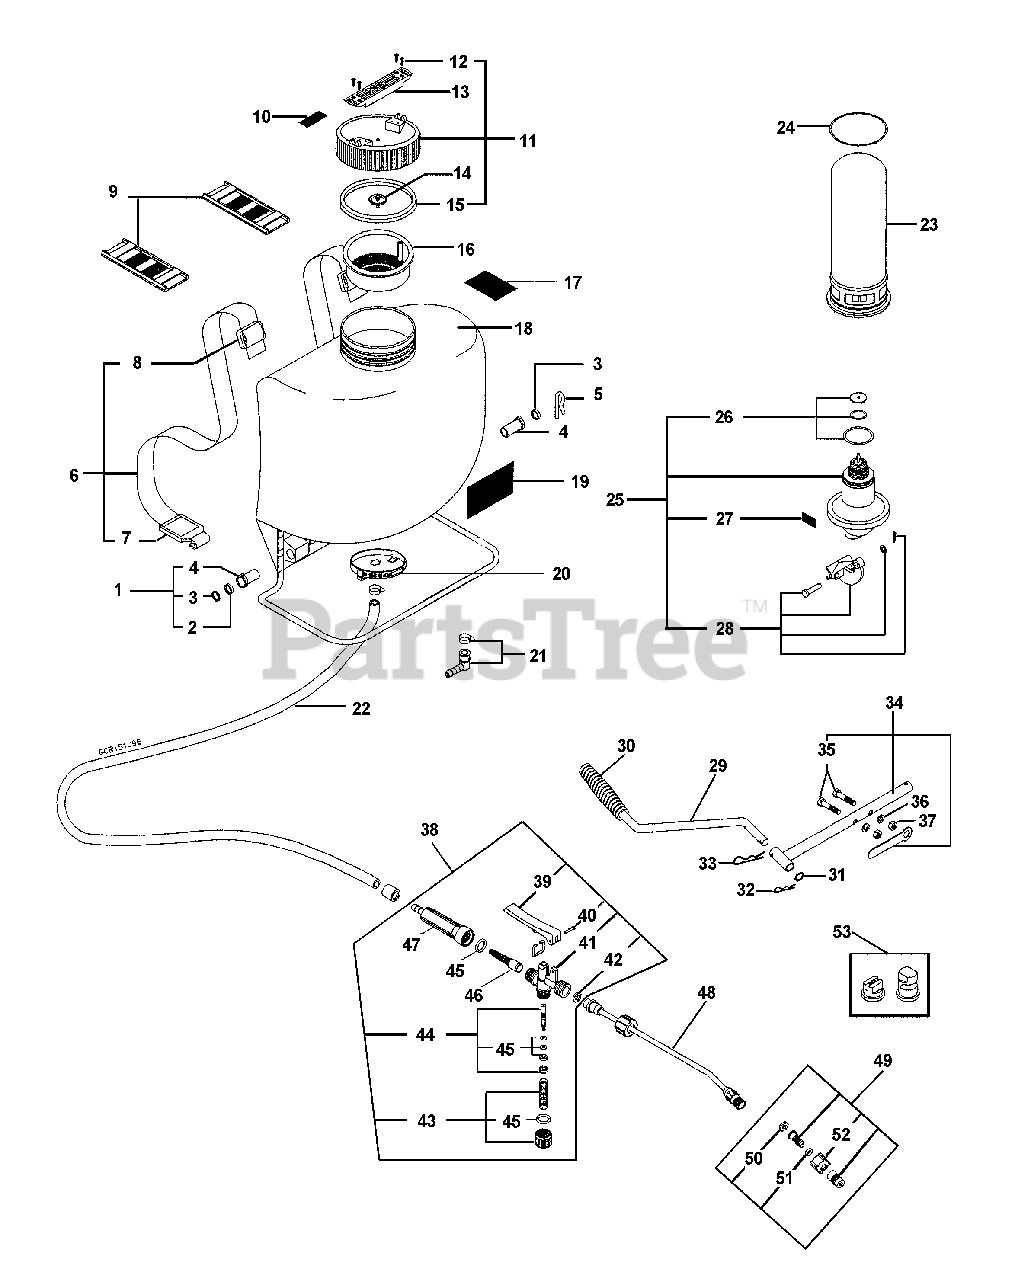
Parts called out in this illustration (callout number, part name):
1	BEARING - NYLON
2	WASHER - NYLON
3	WASHER
4	BUSHING, NYLON
5	PIN, HAIR
6	STRAP ASSY
8	CLIP
9	PAD, SHOULDER STRAP
10	LABEL - CAUTION
11	CAP ASSY
12	SCREW
13	HANDLE
14	VALVE, CHECK
15	SEAL, CAP
16	STRAINER, DEBRIS
17	LABEL - CAUTION
18	TANK
19	LABEL - CAUTION
20	CLAMP
21	FITTING - 90°
22	HOSE
23	TANK, PRESSURE
24	O-RING
25	MODULE DIAPHRAGM PUMP
26	O-RING KIT
27	LABEL - CAUTION
28	CRANKSHAFT ASSY
29	HANDLE, PUMP
30	GRIP
31	WASHER
32	PIN KIT
33	HAIR PIN - LARGE
34	LEVER, PUMP
35	SCREW - SET
36	WASHER
37	NUT
38	SPRAY PISTOL ASSY
39	LEVER, SPRAY PISTOL
40	PIN, LEVER
41	BODY, PISTOL
42	WASHER
43	PLUG SET
44	SPINDLE SET
45	O-RING KIT
46	FILTER
48	WAND - BRASS
49	BRASS NOZZLE ASSY
50	WASHER
51	O-RING
52	NOZZLE HOLDER KIT
53	SPRAY TIP SET
